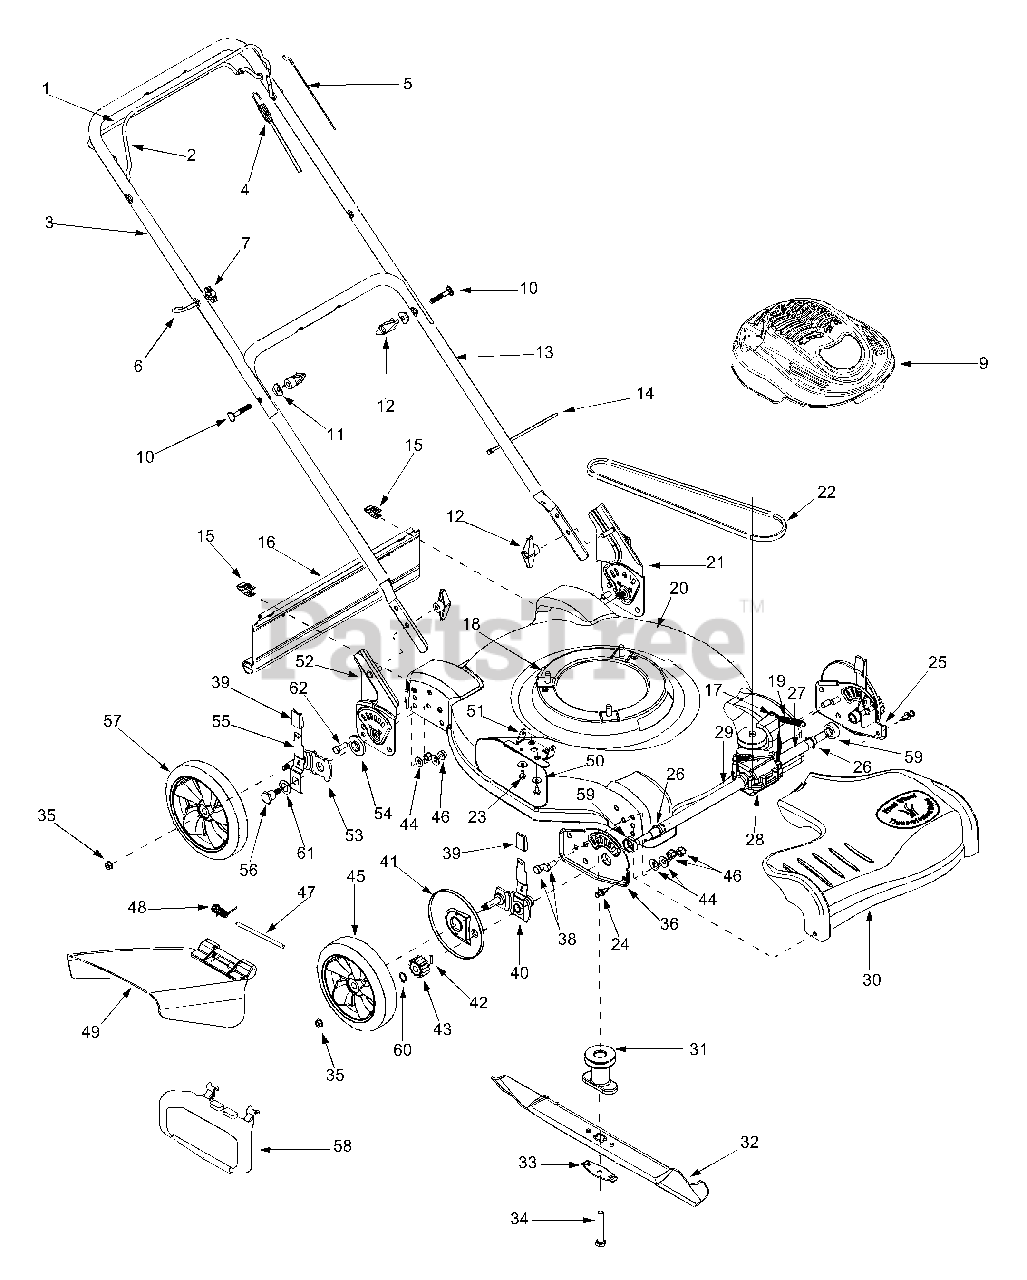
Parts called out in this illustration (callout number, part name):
1	Drive Control Handle
4	Drive Control Cable
5	Blade Control Cable - Tec. (50.56")
6	Eye Bolt
7	Wing Nut 1/4-20
9	Engine Shroud
10	Carriage Bolt 5/16-18 x 2.0
11	Shoulder Washer.320 ID x.93 OD
12	Wing Nut 5/16-18
14	Cable Tie
15	Hinge Clip
16	Trail Shield
17	Screw (Included with Item #28)
18	Hex Washer Screw 3/8-16 x 1.0
19	Spring.47 OD x 2.50
22	V-Belt
23	Hex Washer Screw 1/4-20 x.500
24	Rivet
26	Retainer Ring
27	Sleeve Spacer.550 ID X 3.30
28	Transmission Assembly Complete
29	Sleeve Spacer.550 ID x7.95
30	Transmission Cover
31	Blade Adapter, One Piece
32	Mulching Blade 22"
33	Bell Blade Support
34	Hex Cap Screw 3/8-24 x 1.5
35	Lock Nut 3/8-16
38	Hex Cap Screw 3/8-16 x 1.00
39	Adjustment Knob
40	Spring Lever Assembly - Not Pictured
40	Spring Lever Assembly - Pictured
41	Wheel Dust Cover
42	Pin
43	Spur Gear 14T - LH
43	Spur Gear 14T - RH
44	Washer Spacer.401 ID x.870 OD
45	Front Wheel Assembly 8 x 1.8
46	Hex Lock Nut 3/8-16
47	Hinge Pin
48	Torsion Spring
49	Side Discharge Assembly
50	Bell Washer.265 ID x.75 OD
51	Deflector Chute Adapter
54	Height Adjustment Bearing
55	Spring Lever
56	Shoulder Screw 3/8-16
57	Rear Wheel 8 x 1.8
58	Snap Mulching Plug (If Equipped)
59	Bearing Spacer
60	Snap Ring.500
61	Bell Washer.760 ID x 1.25 OD
62	Hex Cap Screw 3/8-16 x 1.0
